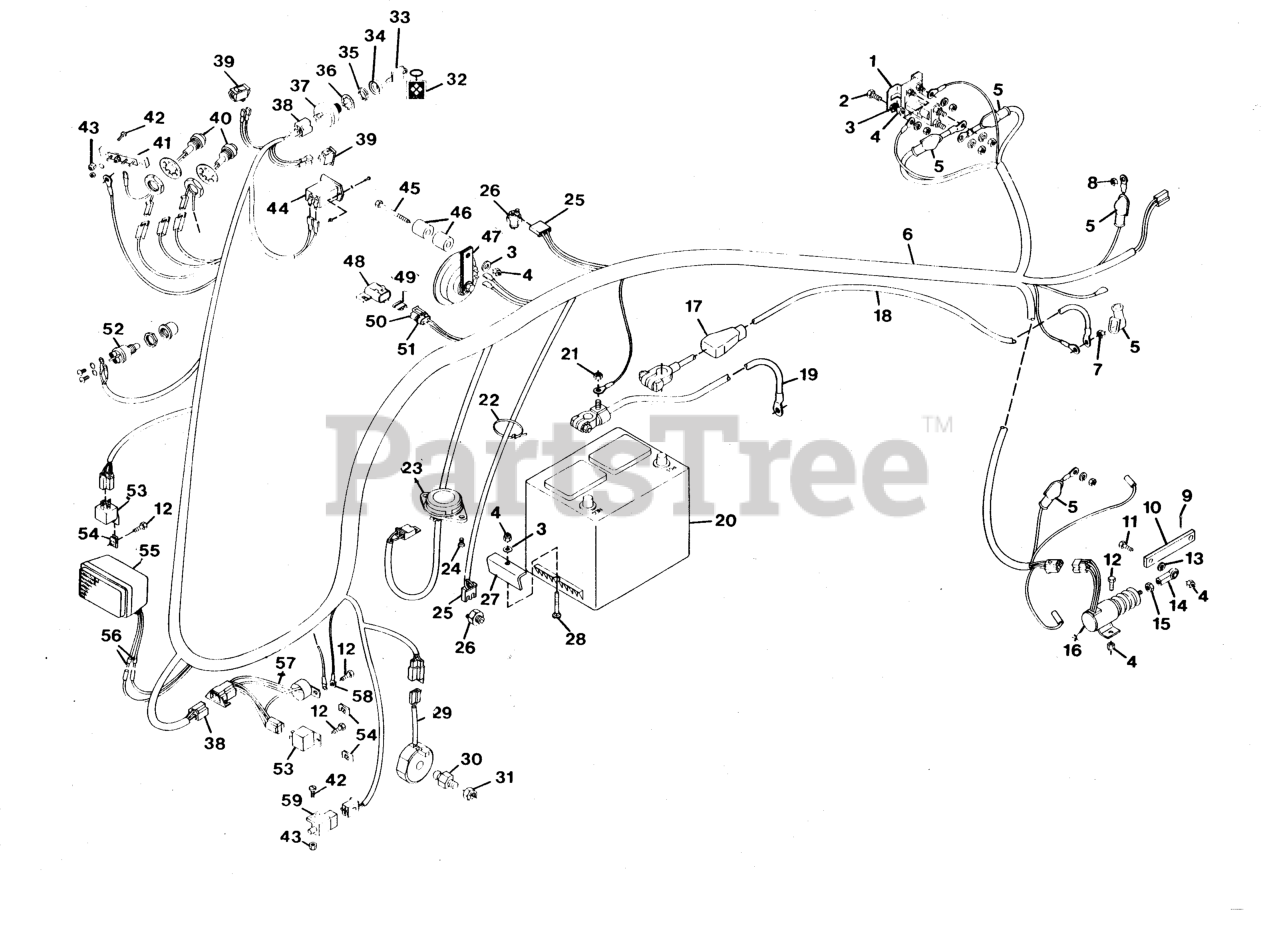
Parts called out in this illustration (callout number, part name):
1	Switch, Magnetic
2	Bolt, Hex 1/4-20x.75
3	Washer, Flat .281x.625x.065
4	Nut, Lock 1/4-20
5	Boot, Battery Cable
6	Nut, 6mm
7	Nut, Hex M8x1.25
8	Pin, Cotter .06x.75
9	Plate, Stop
10	Washer, Lock 1/4 Reg.
11	Bolt, Hex 1/4-20x1.00
12	Nut, Jam 1/4-28 Hex
13	Rod End, Female 1/4-28
14	Bolt, Hex 1/4-20x.625
15	Solenoid, Engine Stop
16	Harness, Wiring
17	Cover, Battery Terminal
18	Cable, Positive Battery
19	Cable, Negative Battery
20	Rod, Hold Down
21	Rod, Battery
22	Nut, Hex 5/16-18
23	Tie Wrap, Black
24	Switch, Seat
25	Screw, Machine 1/4-20x.50
26	Connector, 2-Wire Switch
27	Switch, Interlock
28	Battery, 24-F
29	Assembly, Magnet
30	Pin, Magnet
31	Nut, Lock 1/2-13
32	Chain, Key
33	Key, Ignition Switch
34	Boot, for 9/16 Switch Nut
35	Nut, 9/16-24 for Switch
36	Washer, Lock
37	Switch, Ignition
38	Connector
39	Switch, Light
40	Screw, Machine 10-24x.625 PHD
41	Nut, Lock 10-24
42	Block, Terminal
43	Light, Indicator
44	Hourmeter
45	Bolt, Hex 1/4-20x2.75
46	Bush., St. .406x.100x.1.00 Stl.
47	Horn, 12-V
48	Cover
49	Fuse, 25 Amp
50	Terminal, 14-16 Gauge
51	Connector
52	Switch, Preheater
53	Relay
54	Nut, Speed 1/4-20
55	Headlamp, 3 x 5 Halogen
56	Terminal, Male
57	Terminal, Ring Tongue
58	Module, Time Delay
59	Switch, Interlock
